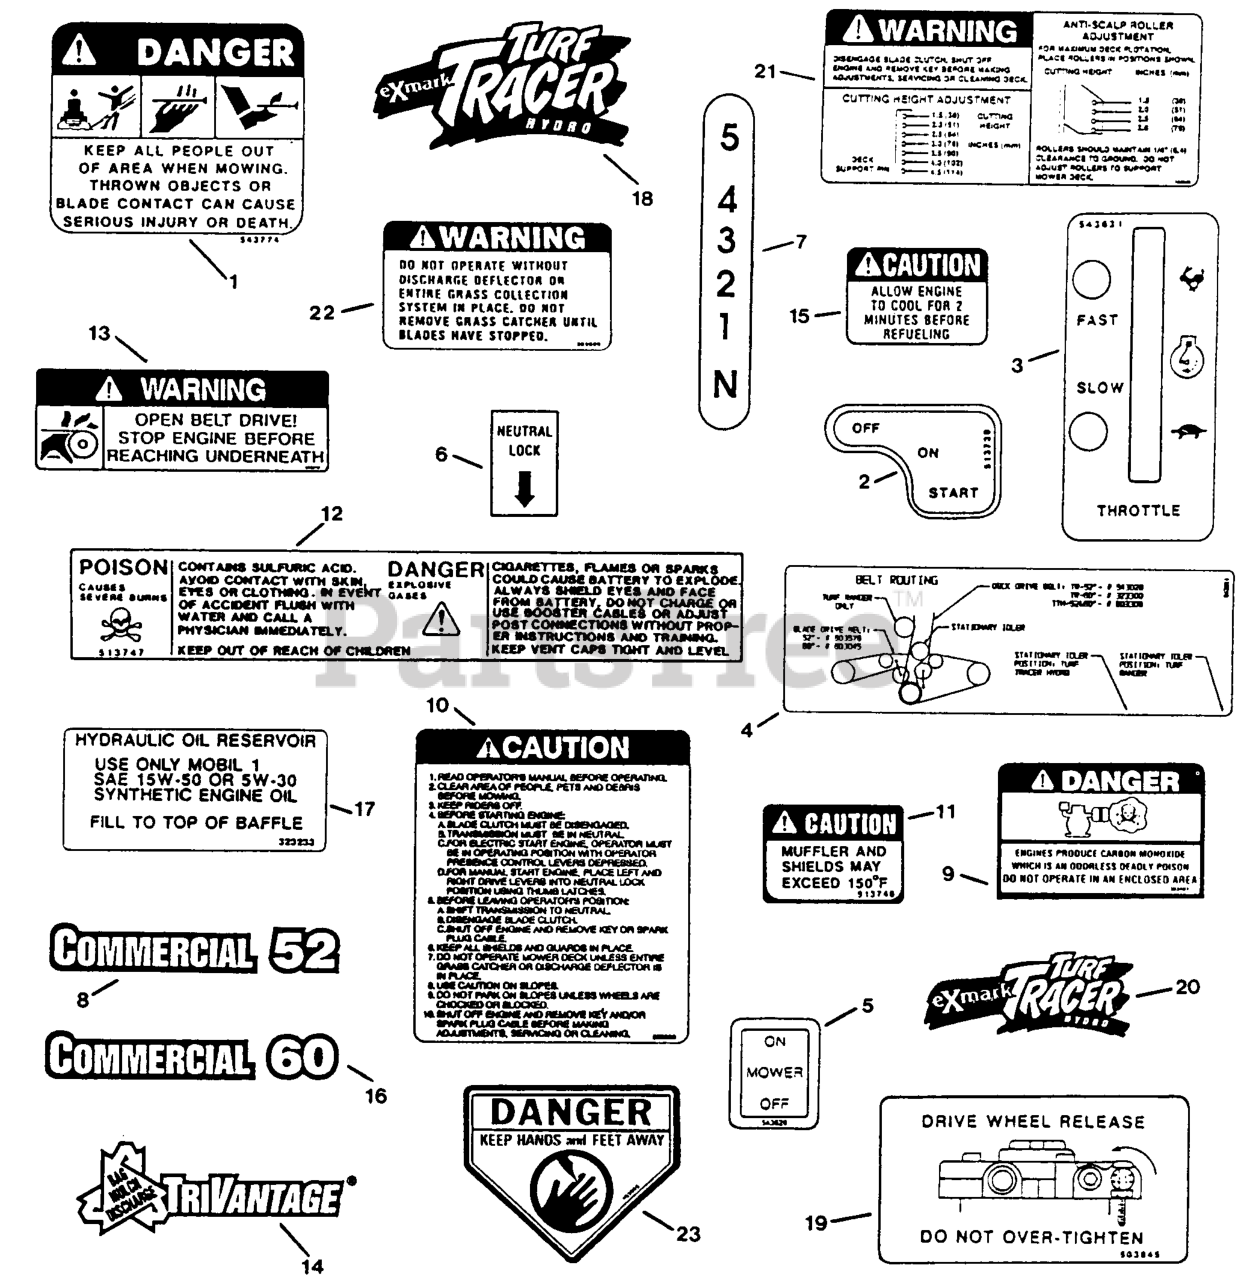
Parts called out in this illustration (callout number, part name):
1	DECAL-DANGER
5	DECAL-MOWER SWITCH
6	DECAL,NEUTRAL LOCK
7	DECAL - SHIFTER
8	DECAL,COMMERCIAL 52
12	DECAL-BATTERY
13	DECAL,BELT DRIVE
16	DECAL,COMMERCIAL 60
17	DECAL,HYD TANK
19	DECAL,DRIVE RELEASE
22	DECAL-WARNING, DISCHARGE
23	DECAL-DANGER
